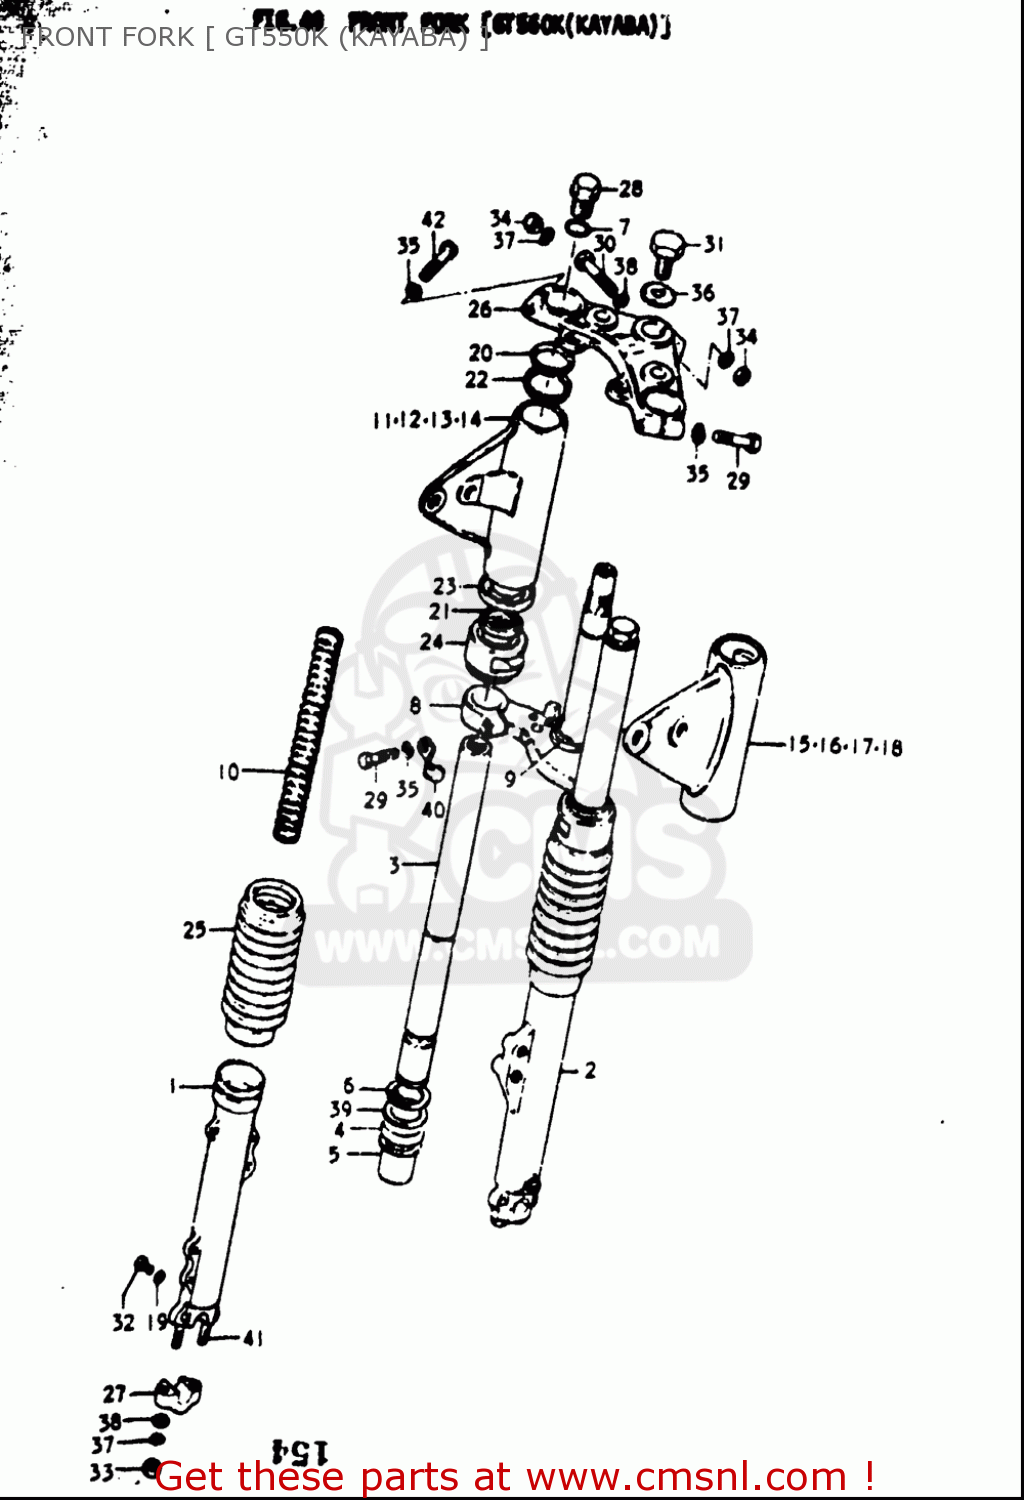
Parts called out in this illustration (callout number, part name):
4	SEAL,OIL
7	O-RING,FORK FITTING BOLT
9	RACE,STEERING OUTER LWR
19	GASKET,DRAIN,PLUG (NAS)
22	GUIDE
23	GUIDE
28	CAP,FORK INNER TUBE
29	BOLT
30	BOLT
32	SCREW
33	NUT
34	NUT
35	WASHER,LOCK
36	WASHER
37	WASHER,LOCK
38	WASHER
41	BOLT,STUD
